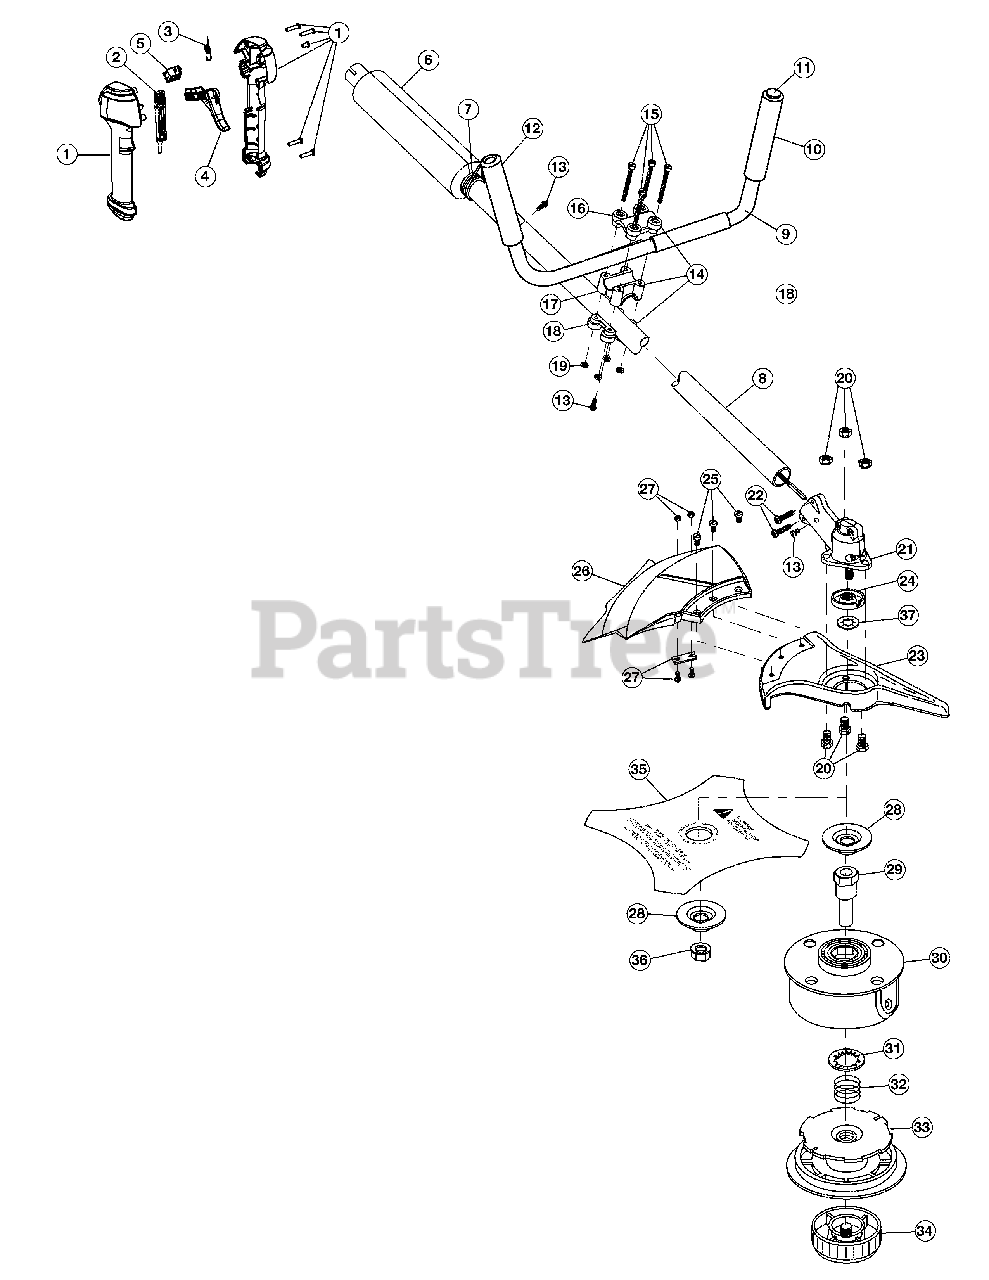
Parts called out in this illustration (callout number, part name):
1	Throttle Housing Assembly (Incl. 2 - 5)
2	Throttle Trigger Lock-Out
3	Throttle Trigger Spring
4	Throttle Trigger
5	Switch Assembly
6	Foam Grip & Cover
7	Harness Clip
8	Drive Shaft Housing Assembly
9	Bullhorn Handle Assembly (Incl. 10 - 13)
11	Plug
12	Adapter
13	Anti-Rotation Screw
14	Handle Bracket Assembly (Incl. 13 & 15 - 19)
16	Upper Handle Clamp
17	Middle Handle Clamp
18	Lower Handle Clamp
20	Shield Mount Screw Assembly
21	2 Piece Gearbox Assembly (Incl. 13, 22, 24 & 37)
22	Gearbox Screw
23	Blade Shield/Shield Mount
24	Blade Driver
25	Shield Mounting Screw
26	Shield Assembly (Incl. 27)
27	Blade Assembly
28	Retaining Washer
29	Spool Shaft
30	Outer Spool Assembly (Incl. 31)
31	Retainer
33	Inner Reel
34	Bump Head Knob Assembly (Incl. 31)
35	4-Tooth Blade
37	Palnut
